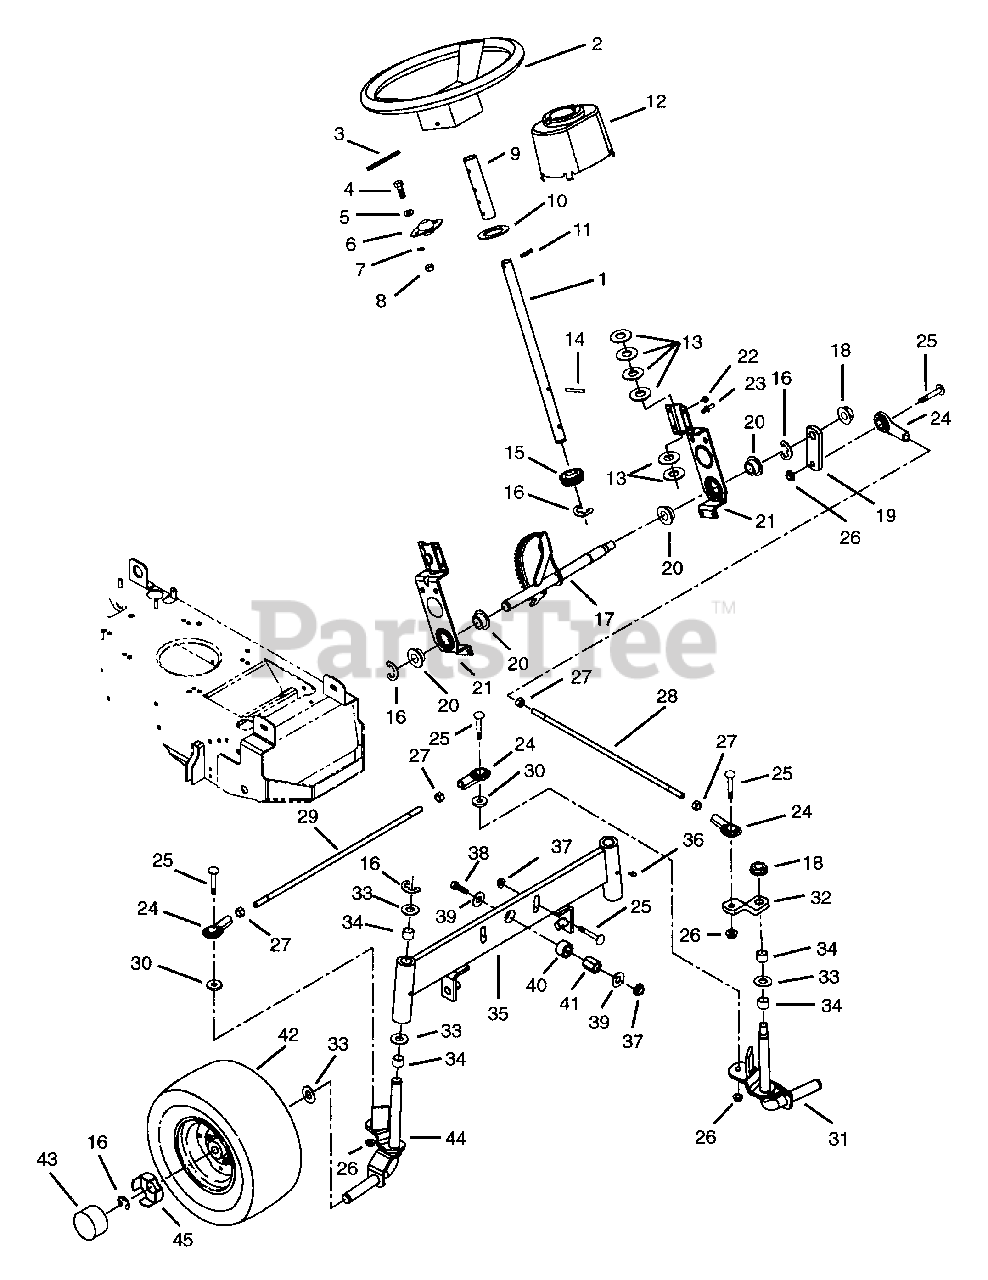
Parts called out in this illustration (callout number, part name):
1	COLUMN, STEERING
2	STEERING WHEEL 13"
3	PIN-ROLL .250X1.75
4	BLT-HEX .31-18X.75 PL GR5
5	WSHR-FL-STL.312X.734X.065PL
6	BRG-FLG .751X2 HOLESX.81
7	WSHR-LK .312X.097 PL HVY
8	NUT-HEX .312-18
9	TUBE .754 X .999 X 5.00
10	WSHR-FL-STL .754X1.125X.062 PL
11	PIN-ROLL .188X1.13
12	CONE- STEERING COLUMN
13	WSHR-FL-STL .755X1.375X.062 PL
14	PIN .249X1.125 DRIV-LOK SP
15	PINION GEAR-STEERING
16	RG-RTNG-EXT .750X.050
17	GEAR, STEERING
18	NUT-LK .563-18 GR 5
19	ARM, STEERING ROD
20	BSHG-FLG .750X1.093X.625X1.375
21	BRACKET, STEERING GEAR
22	SCR-TAP .250-20X.37 HWH PL TR
23	FTG-LUBE .25-28X.256 YWZC
24	ROD END, .38 RH
25	BLT-BTHD .38-16X1.25 GR5
26	NUT-LK-CTR .375-16 GR A PL
27	NUT .375-24 PL
28	LINK - DRAG
29	ROD, TIE
30	BSHG-SLV .377X.624X.370
31	SPINDLE, L.H.
32	ARM - STEERING SPINDLE
33	WSHR-FL-STL .755X1.375X.093
34	BSHG-SLV .750X.814X .750 BRZ
35	AXLE, FRONT
36	SPIN DRIVE ZERK FITTING
37	NUT-LK-NYL .375-16 PL
38	BLT-HEX .38-16X1.75 PL GR5
39	WSHR-FL-STL .390X1.500X.125
40	BSHG-SLV .626X1.000X.524 HEX
41	BSHG-SLV .377X.623X.775 HEX
42	T/WHL ASSY 15X6.00-6
43	HUB CAP
44	SPINDLE, R.H.
45	SPINDLE CUP
